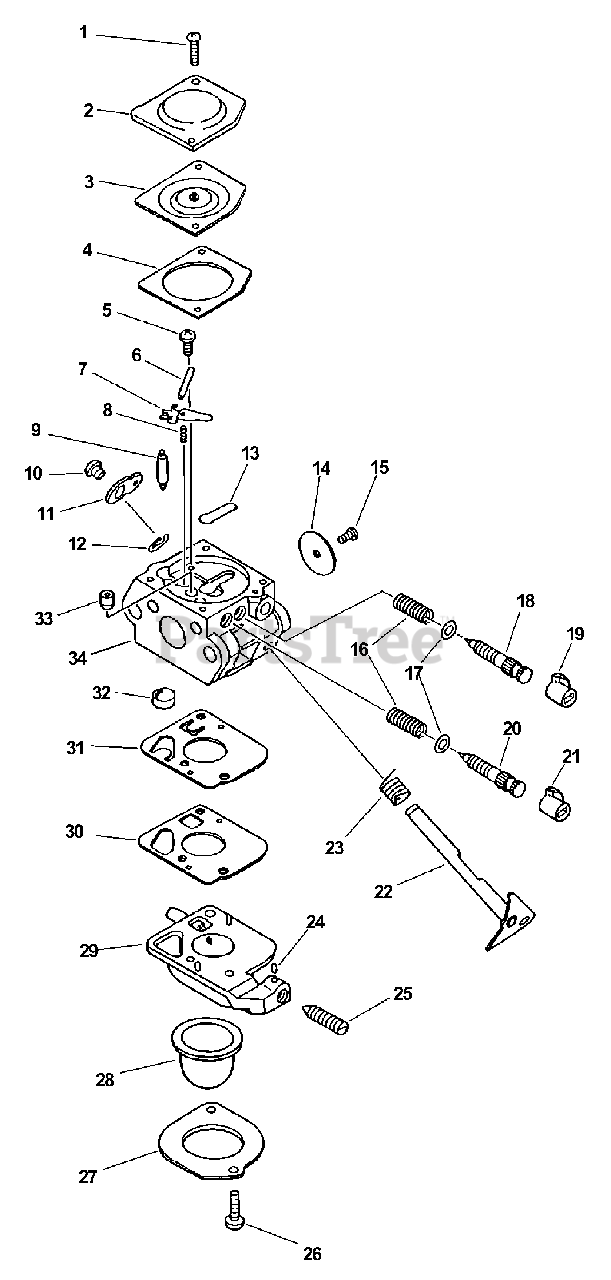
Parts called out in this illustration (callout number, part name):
2	COVER, DIAPHRAGM
3	DIAPHRAGM, METERING
4	GASKET, DIAPHRAGM
6	PIN, METERING LEVER
7	LEVER, METERING
8	SPRING, METERING LEVER
9	VALVE, INLET NEEDLE
12	LEVER, THROTTLE
13	PLUG, WELCH
14	VALVE, THROTTLE
15	SCREW 3×4.5
16	SPRING, NEEDLE
18	NEEDLE, LOW SPEED
19	CAP, LIMITER - WHITE
20	NEEDLE, HIGH SPEED
21	CAP, LIMITER
22	SHAFT, THROTTLE
23	SPRING, THROTTLE RETURN
24	PIECE, FRICTION
27	RETAINER
28	BULB, PURGE
29	BODY ASSY, PURGE
30	GASKET, PUMP
31	DIAPHRAGM, PUMP
32	STRAINER
33	NOZZLE, CHECK VALVE
34	BODY, CARBURETOR
